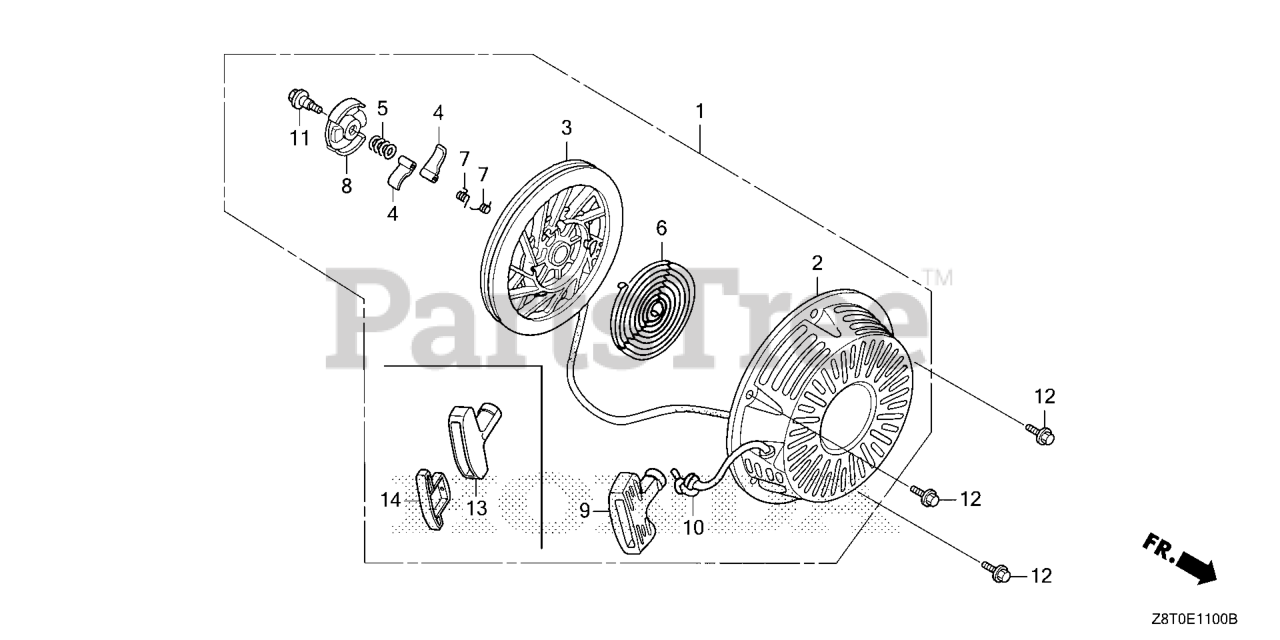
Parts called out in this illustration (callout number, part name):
1	STARTER ASSY., RECOIL *R280* (FOR U.S.A.) (POWER RED)
1	STARTER ASSY., RECOIL *NH1* (FOR U.S.A.) (BLACK)
2	CASE, RECOIL STARTER *NH1* (BLACK)
2	CASE, RECOIL STARTER *R280* (POWER RED)
3	PULLEY, RECOIL STARTER
4	RATCHET, STARTER
5	SPRING, FRICTION
6	SPRING, STARTER RETURN
7	SPRING, RATCHET
8	RETAINER, SPRING
10	ROPE, RECOIL STARTER (#6X64") (N/A: USE P/N 08560-ZG921-11)
11	SCREW, CENTER
12	BOLT, FLANGE (6X10)
13	GRIP, STARTER
14	GRIP, REINFORCEMENT
